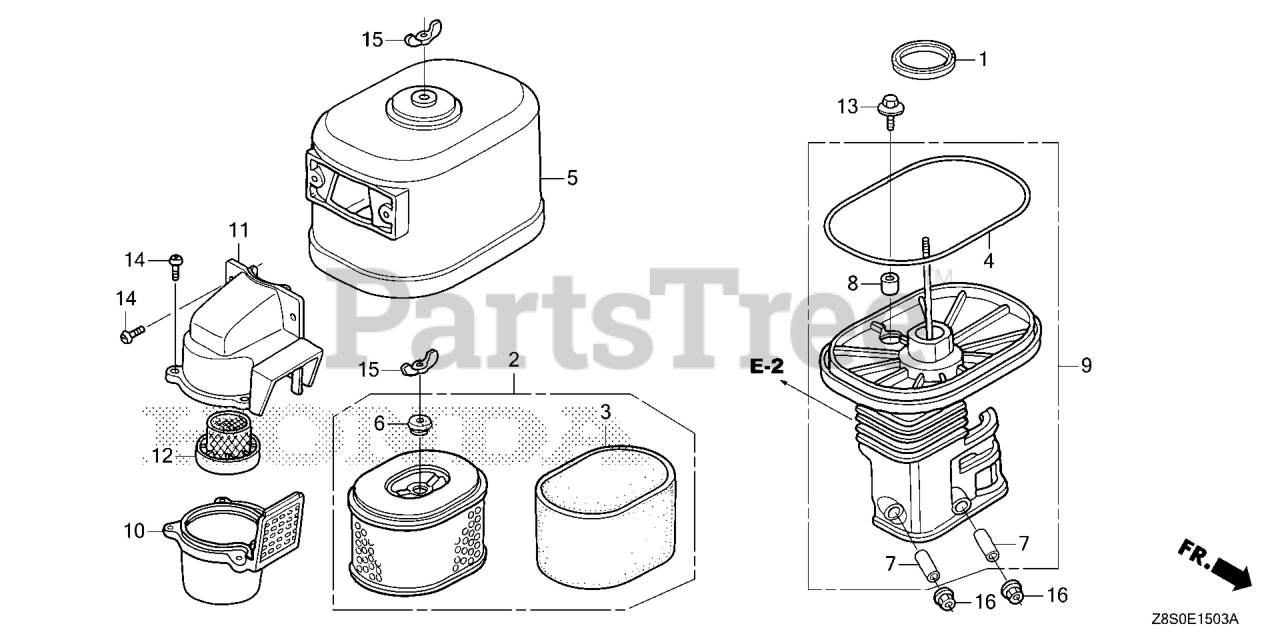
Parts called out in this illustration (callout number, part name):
1	GASKET, ELBOW
2	ELEMENT, AIR CLEANER
3	FILTER (OUTER)
4	SEAL, AIR CLEANER COVER
5	COVER, AIR CLEANER (CYCLONE)
6	GROMMET, AIR CLEANER
7	COLLAR, AIR CLEANER
8	COLLAR B, AIR CLEANER
9	ELBOW, AIR CLEANER
10	CASE, PRE AIR CLEANER
11	CAP, PRE AIR CLEANER
12	GUIDE, PRE AIR CLEANER
13	BOLT-WASHER (6X22)
14	SCREW, PAN (5X16.5)
15	WINGNUT, TOOL BOX SETTING
16	NUT, FLANGE (6MM)
